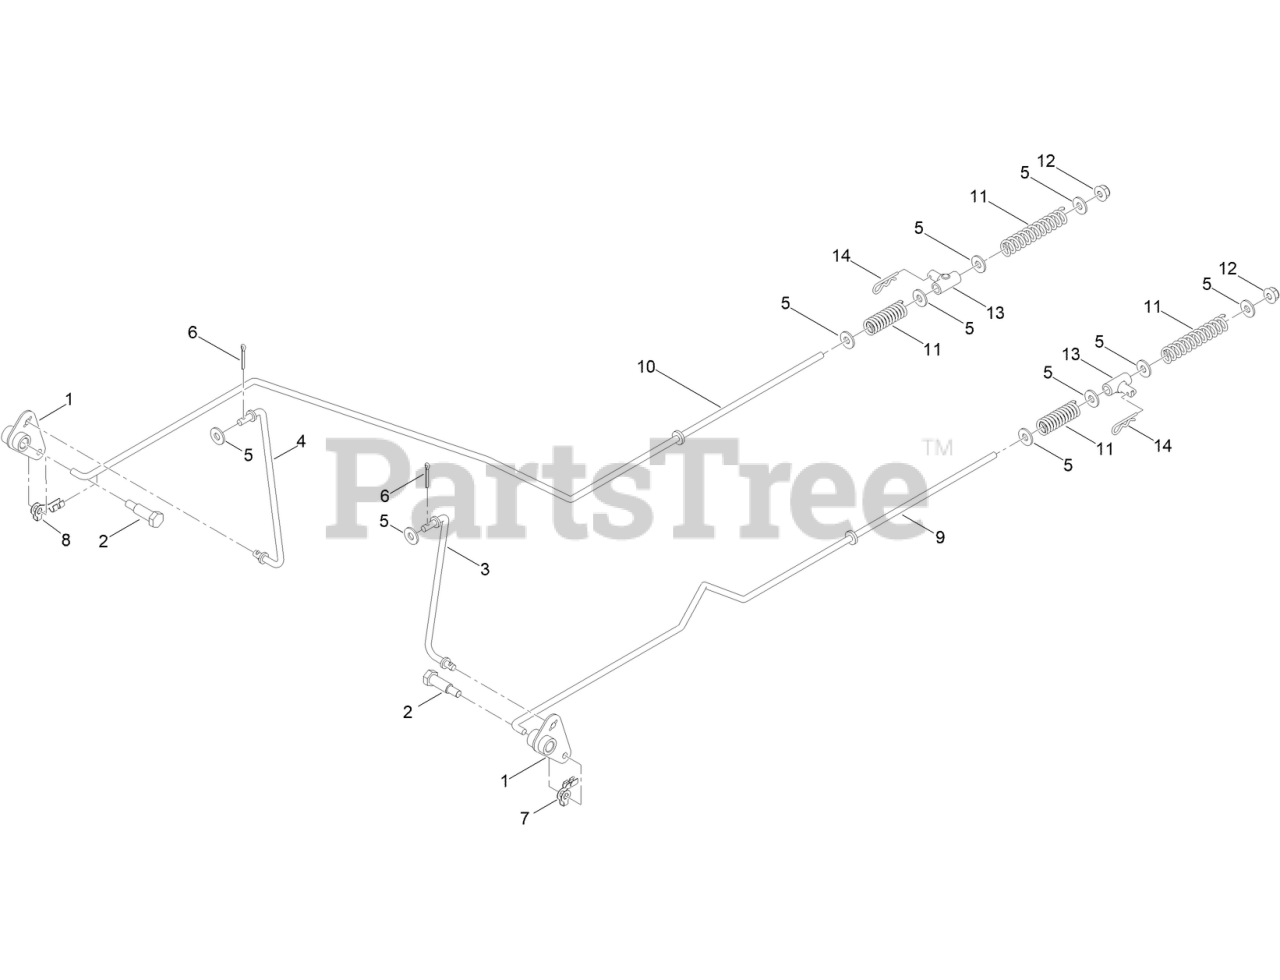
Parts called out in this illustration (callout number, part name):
1	BELLCRANK
2	BOLT-SHOULDER
3	LINK-BRAKE, LH
4	LINK-BRAKE, RH
5	WASHER
6	PIN-COTTER
7	CLIP-ROD, LH (7L, 1/4IN)
8	CLIP-ROD, RH (7R, 1/4IN)
9	ROD-BRAKE LH
10	ROD-BRAKE, RH
11	SPRING-COMPRESSION
12	NUT-FLANGE, NI
13	MOUNT-PIVOT
14	PIN-HAIR
